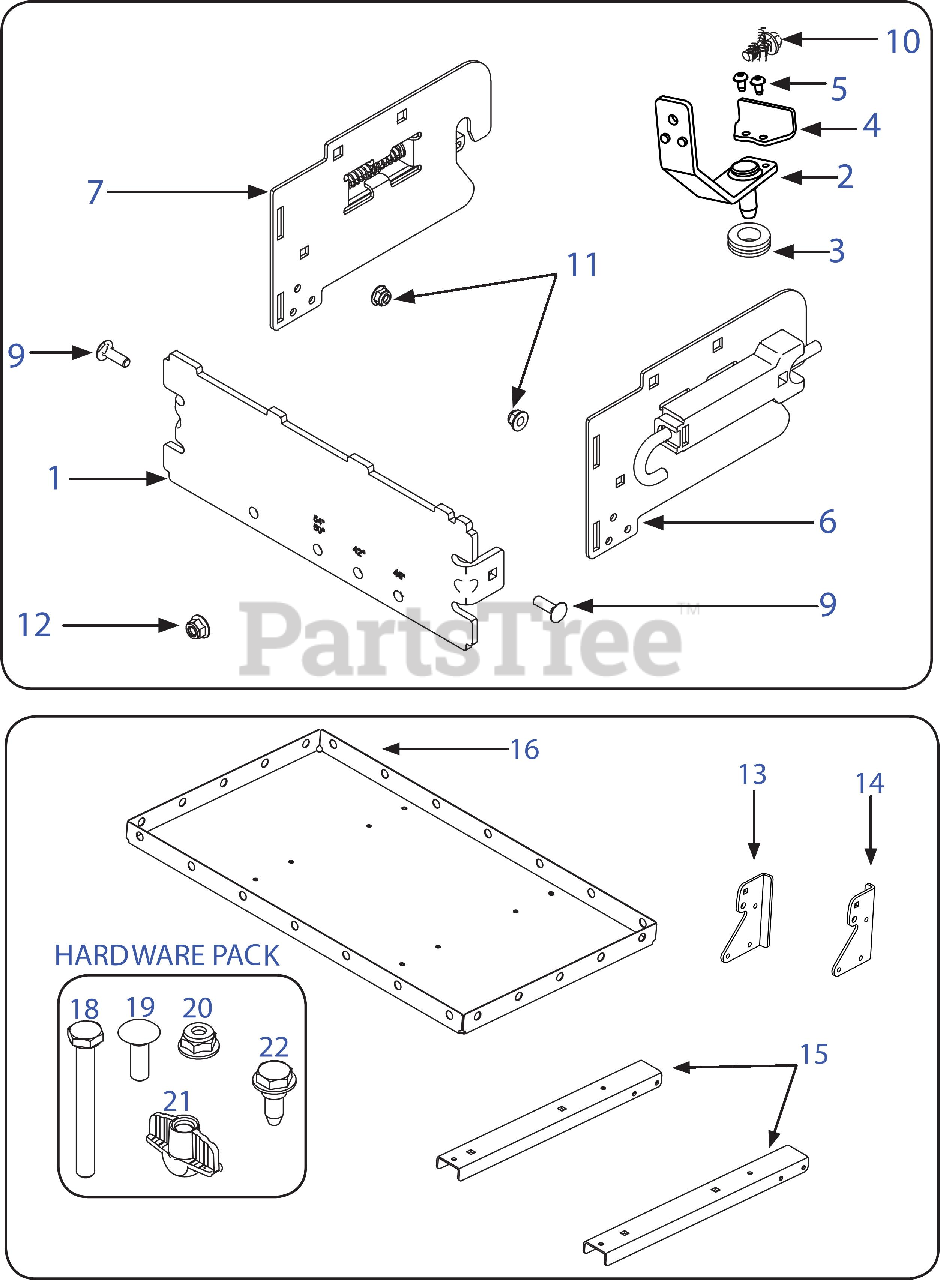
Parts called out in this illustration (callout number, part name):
2	Pin Hitch Support Assembly
3	Rubber Grommet
4	Hitch Support Bracket
5	Torx Screw: 1/4-20
6	RH Bracket Assembly
7	LH Bracket Assembly
9	Carriage Screw: 5/16-18: 1.0
10	Hex Screw: 3/8-16: 1.0
11	Nylon Lock Nut: 5/16-18
12	Flange Lock Nut: 3/8-16
13	LH Cargo Hinge Bracket
14	RH Cargo Hinge Bracket
17	Cargo Carrier Hardware Pack
18	Hex Screw: 1/4-20: 2.25
19	Carriage Screw: 1/4-20: .75
20	Flange Lock Nut: 1/4-20
21	Wing Nut: 1/4-20
22	Shoulder Screw: .3175 x .188: 1/4-20
